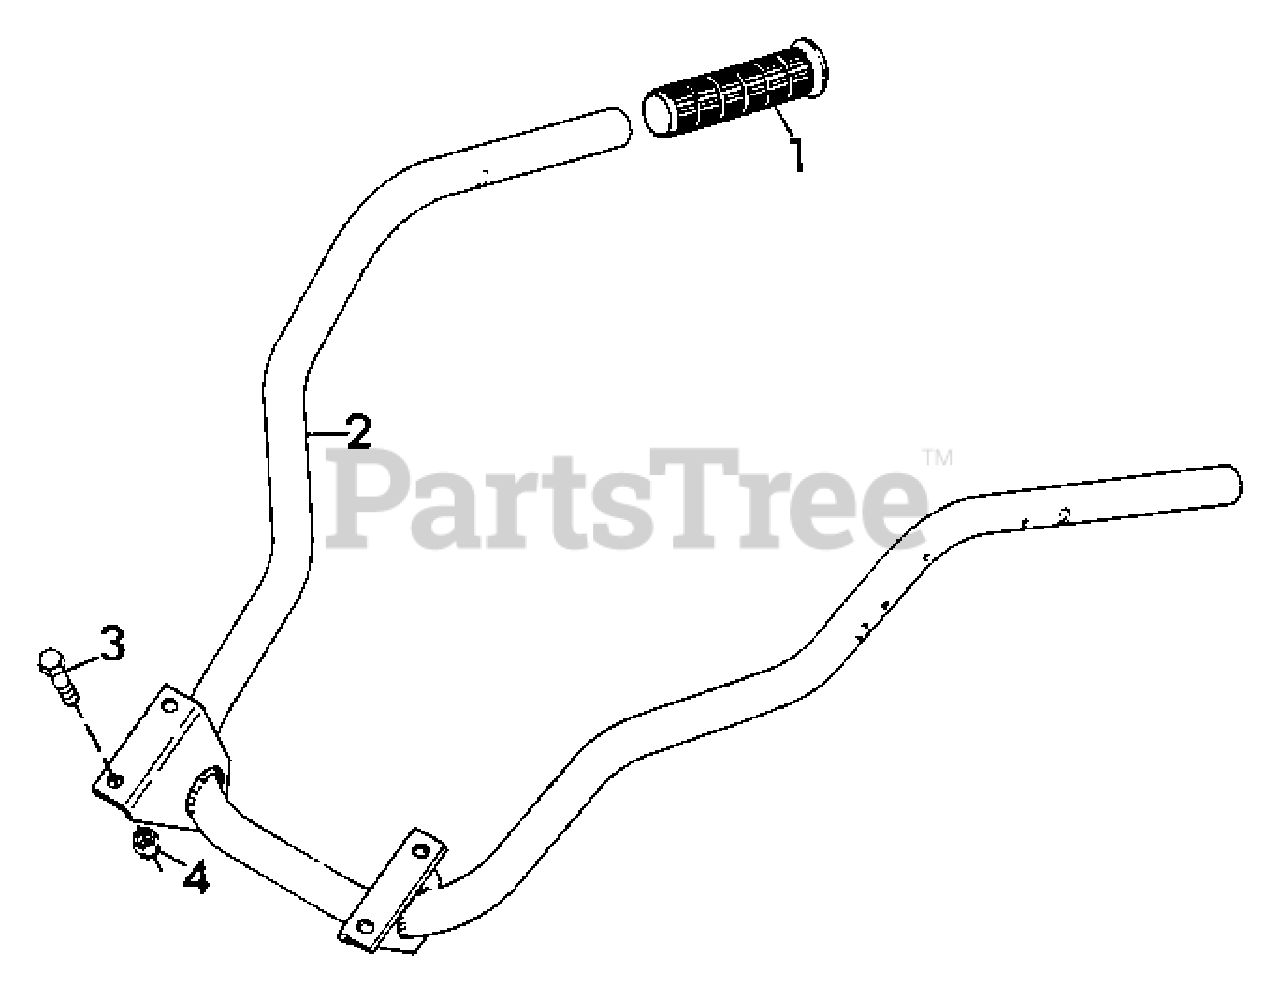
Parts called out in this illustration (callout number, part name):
1	Grip, Handlebar
2	Weldment, Handlebar
3	Bolt, Hex 3/8-16x1.25 Gr. 8
4	Nut, Lock 3/8-16
